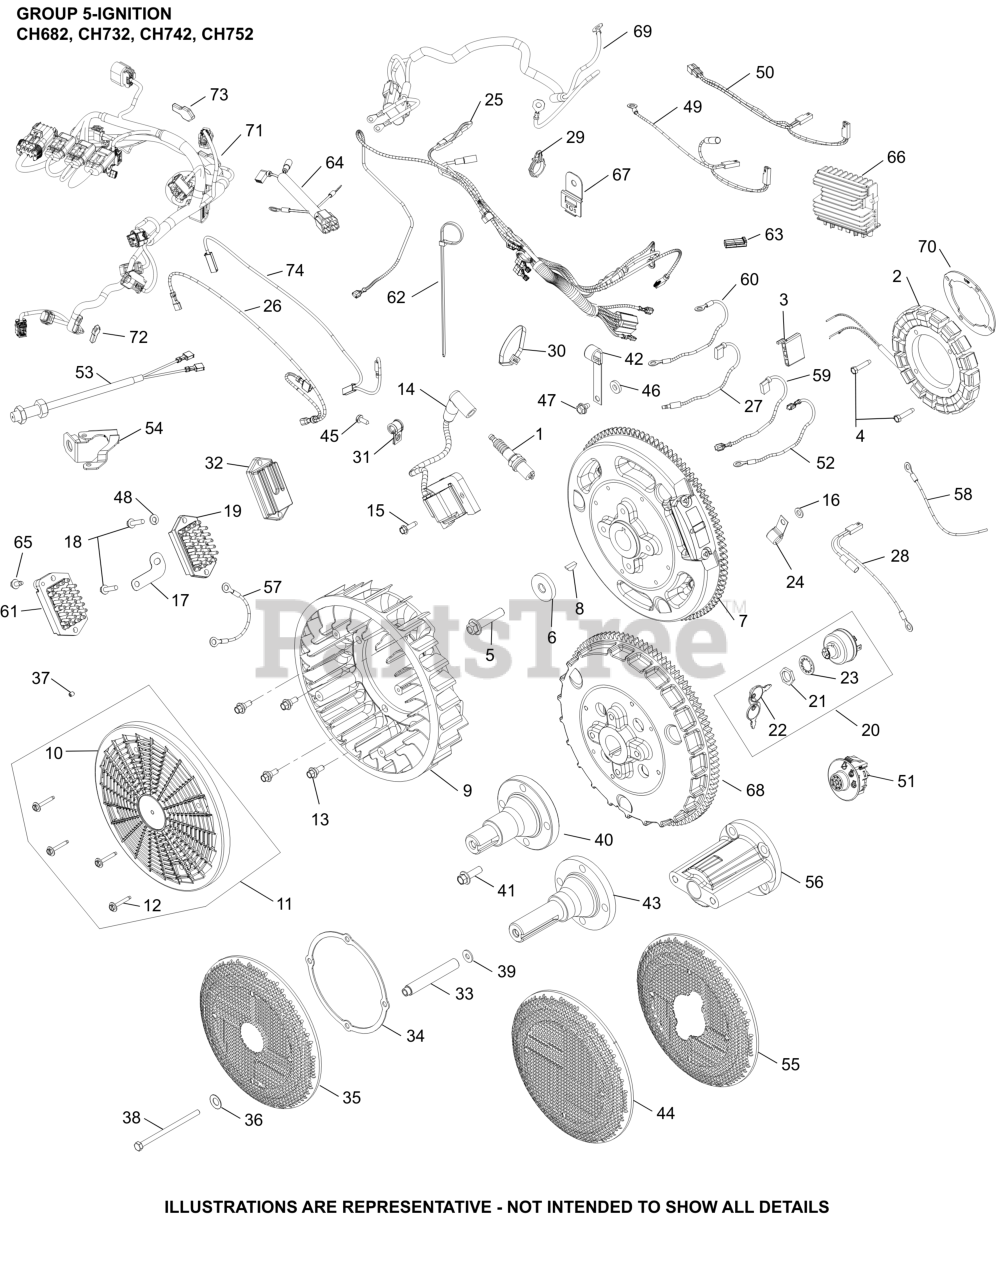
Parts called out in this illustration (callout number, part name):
1	PLUG, SPARK (PRO SERIES)
2	KIT, 15 / 20 AMP STATOR
3	CONNECTOR
4	SCREW, THREAD FORMING
5	SCREW, FLG M10X1.5X45-USE 25 086 361-S
6	WASHER, FLAT 13/32"
7	FLYWHEEL ASSEMBLY (LW)
8	KEY, 3/16" X 5/8"
9	FAN-USE 24 755 253-S
10	SCREEN, GRASS
11	KIT GRASS SCREEN
12	SCREW, FLG SEMS M4x.7x25
13	BOLT, SHOULDER
14	MODULE, MAGNETO DIGITAL IGNITION
15	SCREW, THREAD FORMING
16	WASHER, FLAT 1/4" (O.D. 1/2")
18	SCREW, HEX FLANGE HI-LO
24	CLIP, CABLE
25	HARNESS WIRING ASSEMBLY
26	LEAD, DUPLEX
27	LEAD, OIL SENTRY
28	LEAD, JUMPER (H/S)
29	RETAINER, WIRE HARNESS
52	LEAD, 20/25 AMP B+
61	REGULATOR, RECT (20-30AMP, FW W/OVP)
65	SCREW, THREAD FORMING
